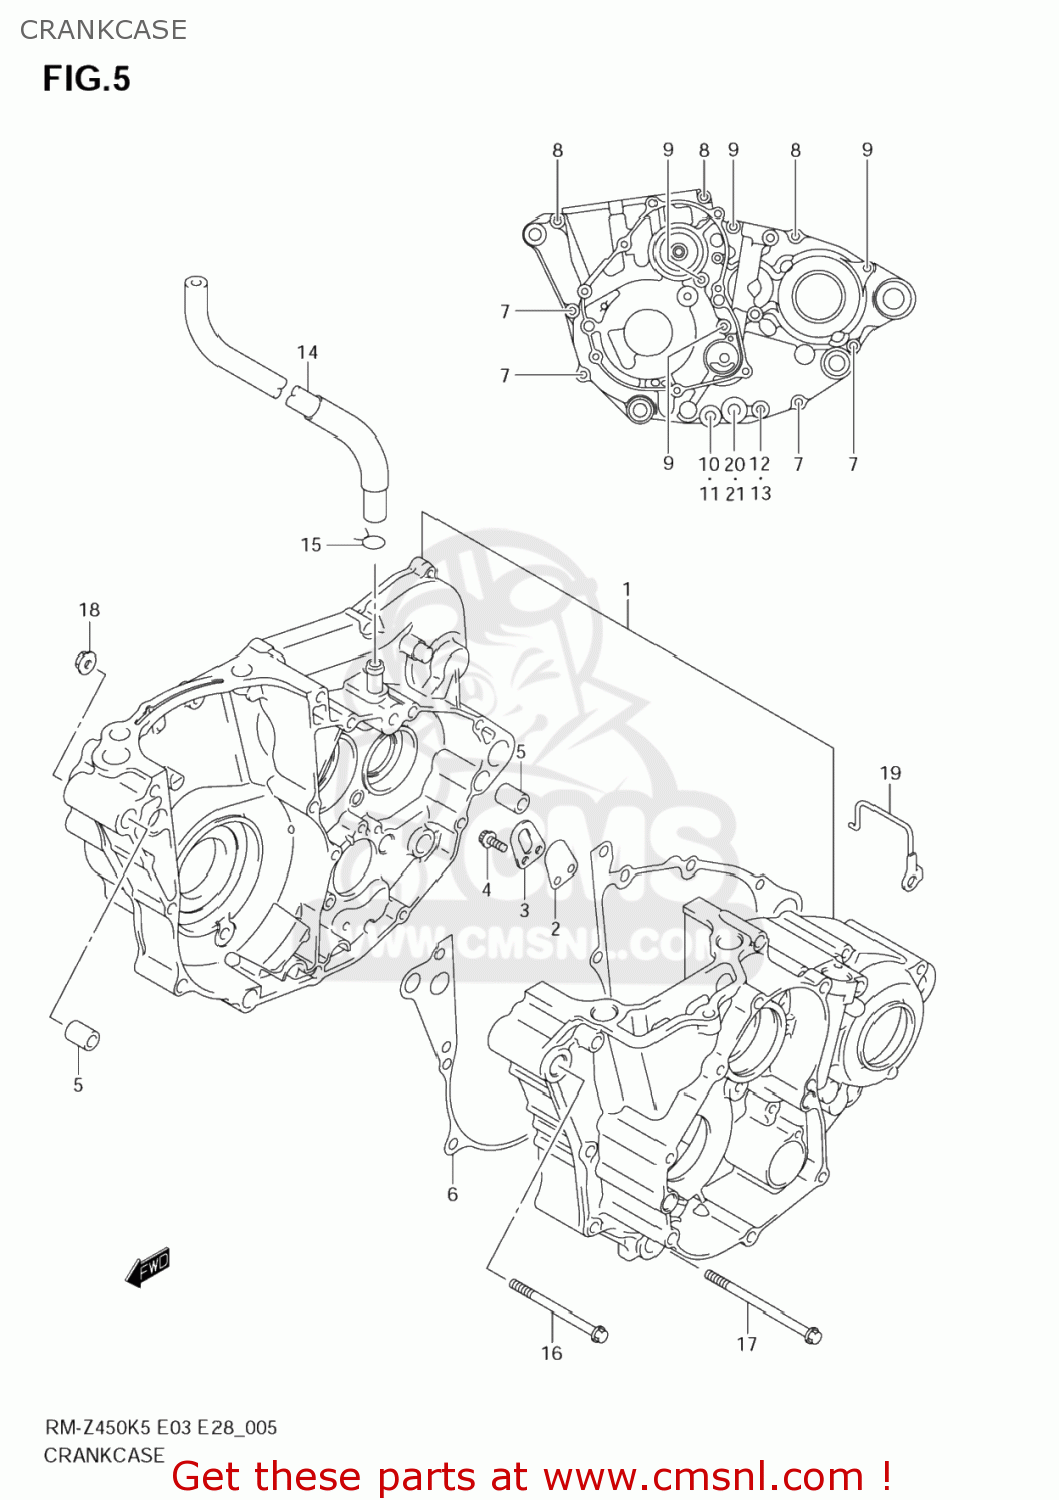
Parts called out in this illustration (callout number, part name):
1	CRANKCASE SET
2	VALVE,CRANKCASE REED
3	STOPPER,CRANKCASE REED VALVE
4	BOLT
5	PIN(10.4X13X18)
6	GASKET,CRANKCASE (NAS)
7	BOLT(6X55)
8	BOLT(6X65)
9	BOLT(6X75)
10	BOLT(8X45)
11	GASKET(8.2X14X1) (NAS)
12	BOLT(8X16)
13	GASKET(8.2X14X1) (NAS)
14	HOSE,BREATHER
15	CLIP
16	BOLT(10X125)
17	BOLT(10X170)
18	NUT
19	GUIDE,CARBURETOR HOSE
20	GASKET OILPLUG (NAS)
21	GASKET(16X22X2) (NAS)
